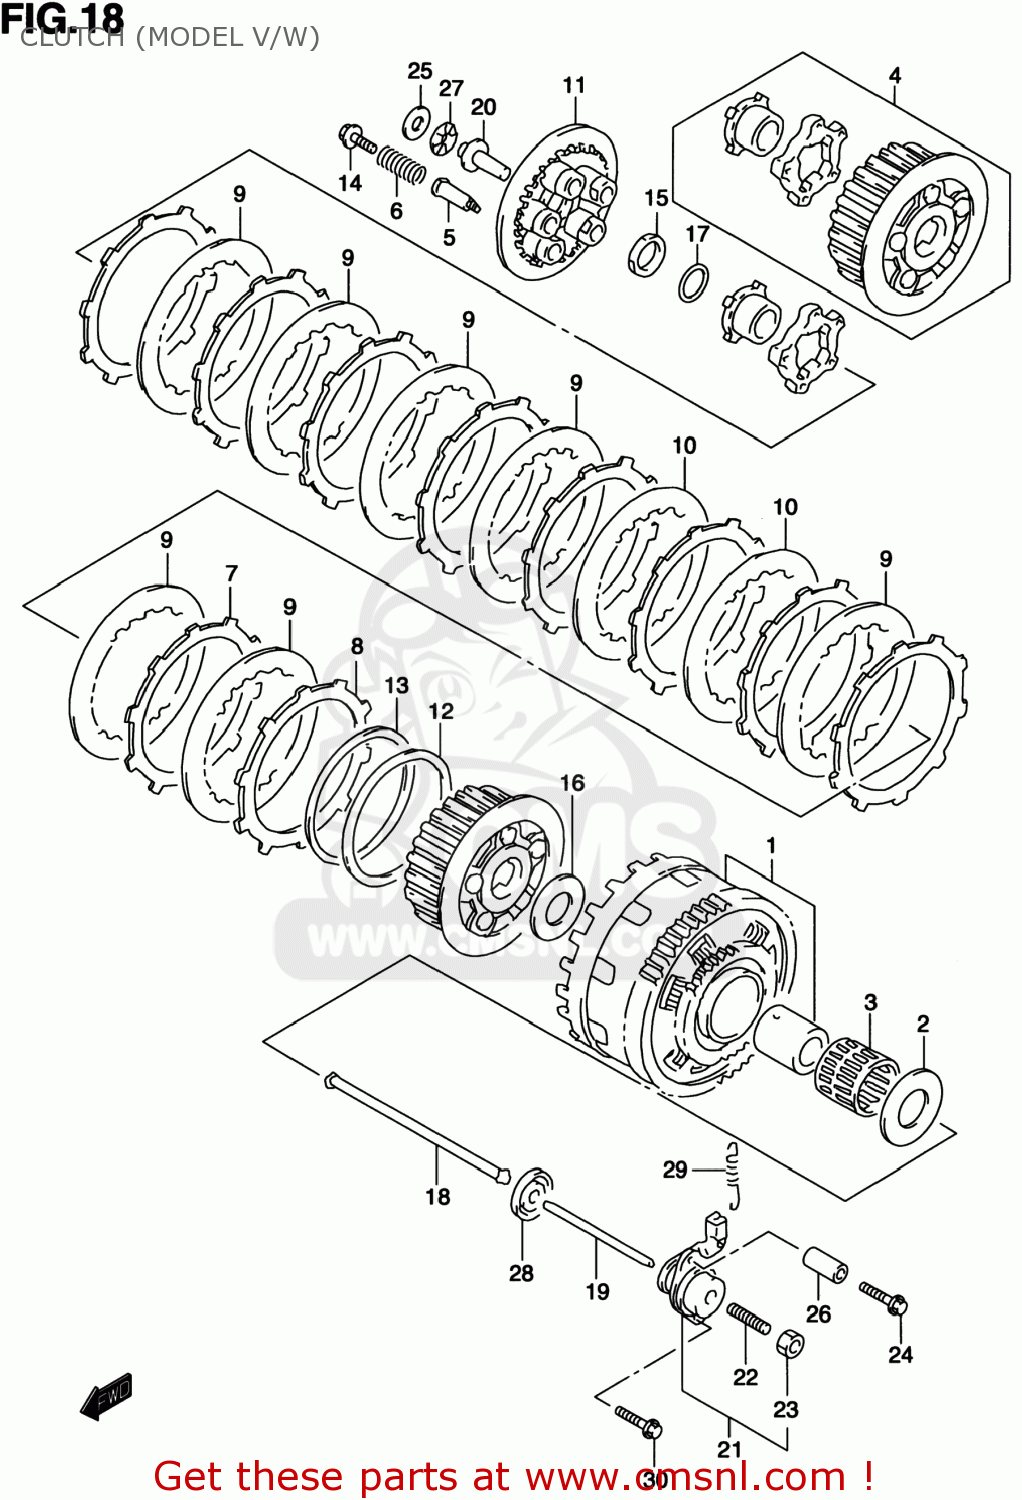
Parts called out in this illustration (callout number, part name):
1	GEAR ASSY,PRI DRIVEN
2	WASHER(25X54X2.5)
3	BEARING(35X40X35.8)
4	CAM SET,CLUTCH
5	BOLT,CLUTCH SPRING SUPPORT
6	SPRING,CLUTCH ASSIST
7	PLATE,CLUTCH DRIVE NO (NAS)
8	PLATE,CLUTCH DRIVE
9	PLATE,CLUTCH DRIVEN NO.1
10	PLATE,CLUTCH DRIVEN NO.2
11	DISC,CLUTCH PRESSURE
12	SEAT,CLUTCH PLATE WAVE WASHER
13	WASHER,CLUTCH PLATE WAVE
14	BOLT,CLUTCH SPRING
15	NUT
16	WASHER(25X50X2.5)
17	WASHER
18	ROD,CLUTCH PUSH,R
19	ROD,CLUTCH PUSH,L
20	PIECE,CLUTCH PUSH
21	SCREW ASSY,CLUTCH RELEASE
22	SCREW(6X25)
23	NUT
24	BOLT
25	WASHER(15.5X28X1)
26	SPACER(6.2X12X50)
27	BEARING(15X28X2)
28	SEAL,OIL(6X34X5.5)
29	SPRING
30	BOLT
31	PLATE SET,CLUTCH
